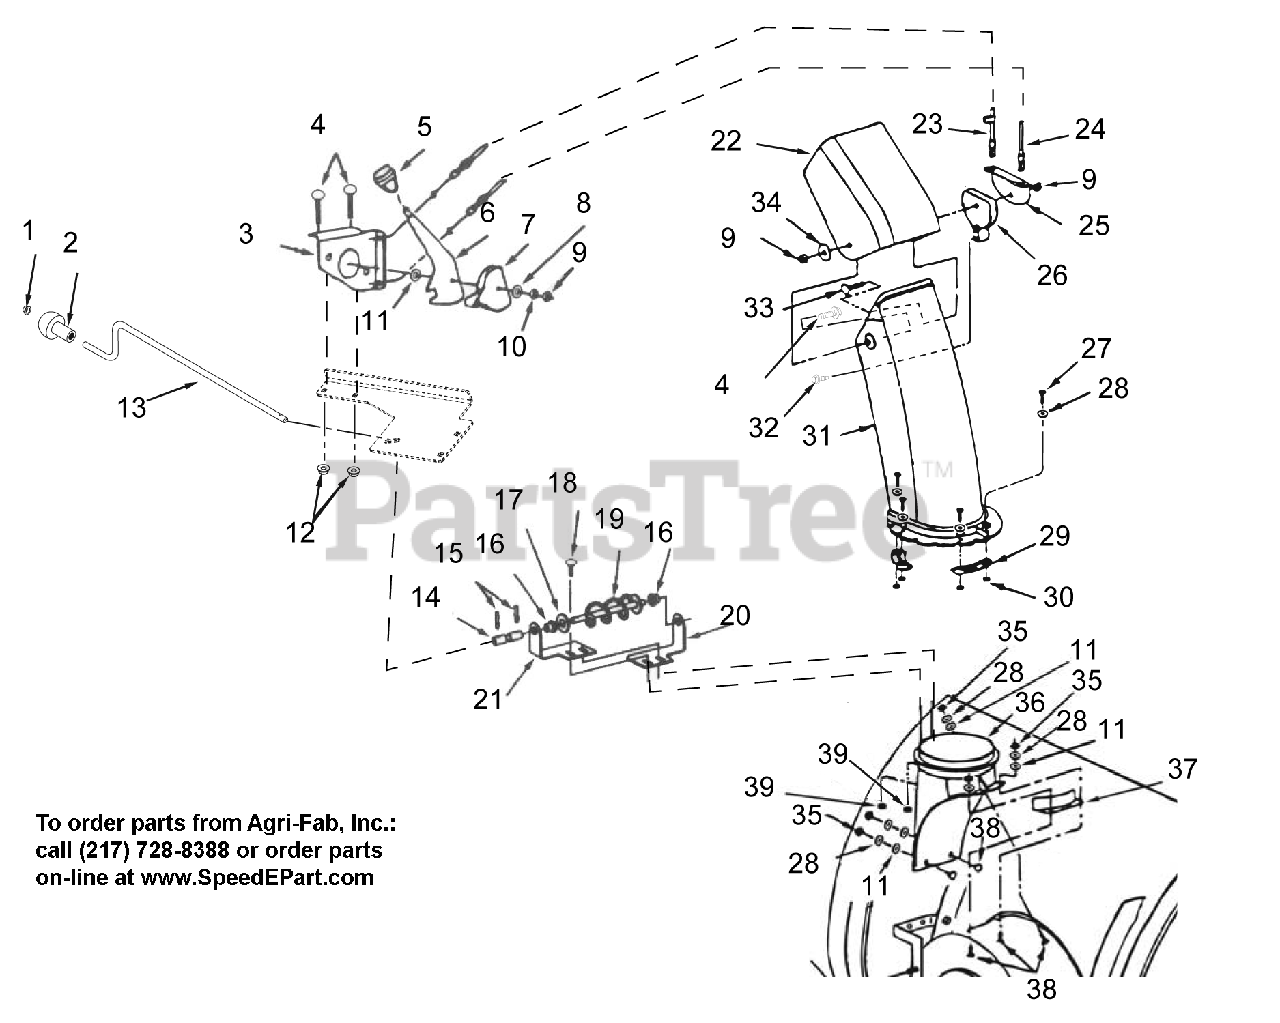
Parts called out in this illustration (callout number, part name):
1	CAP, 3/8 ROD YWZC
2	KNOB
3	Assembly, Chute Tilt Bracket
4	@BLT-RDHDSQNK .31-18X.75 G5YZ
5	Knob
6	Handle, Chute Tilt
7	Guide, Cable
8	@WSHR-FL-STL.344X.688X.065YWZC
9	@NUT-LK-CTR .31-18 YWZC
10	@WSHR-LK .31X.078 REG YWZC
11	WSHR-FL-NY .375X.75X.060
12	@NUT-LK-TOP-FLG .31-18 YWZC
13	CRANK, CHUTE
14	UNIVERSAL JOINT ASS'Y
15	PIN, SPRING CLIP
16	BUSHING,3/8" (AGRI-FAB)
17	@WSHR-FL-STL.406X.812X.065 YWZ
18	@BLT-RDHDSQNK .31-18X1.00 G5YZ
19	WORM,CHUTE CRANK
20	BKT,CHUTE CRANK FRONT
21	BKT,CHUTE CRANK REAR
22	Chute, Upper
23	Cable, Chute Control with Clip
24	Cable, Chute Control
25	Bracket, Cable
26	Guide, Cable
27	@BLT-HEX .25-20X1.00 GR5 YWZC
28	@WSHR-FL-STL.281X.62X.065 YWZC
29	Chute Keeper
30	@NUT-LK-CTR .25-20 YWZC
31	Chute, Lower
32	@SCR-MCH .25-20X.75 HWH YWZC
33	@BLT-RDHDSQNK .31-18X1.50 G5YZ
34	@WSHR-FL-STL.344X.688X.065YWZC
35	@NUT-LK-CTR .25-20 YWZC
36	Chute Adapter
37	Chute Reinforcement
38	@BLT-RDHDSQNK .25-20X.75 G5YZ
39	@NUT-LK-TOP-FLG .31-18 YWZC
